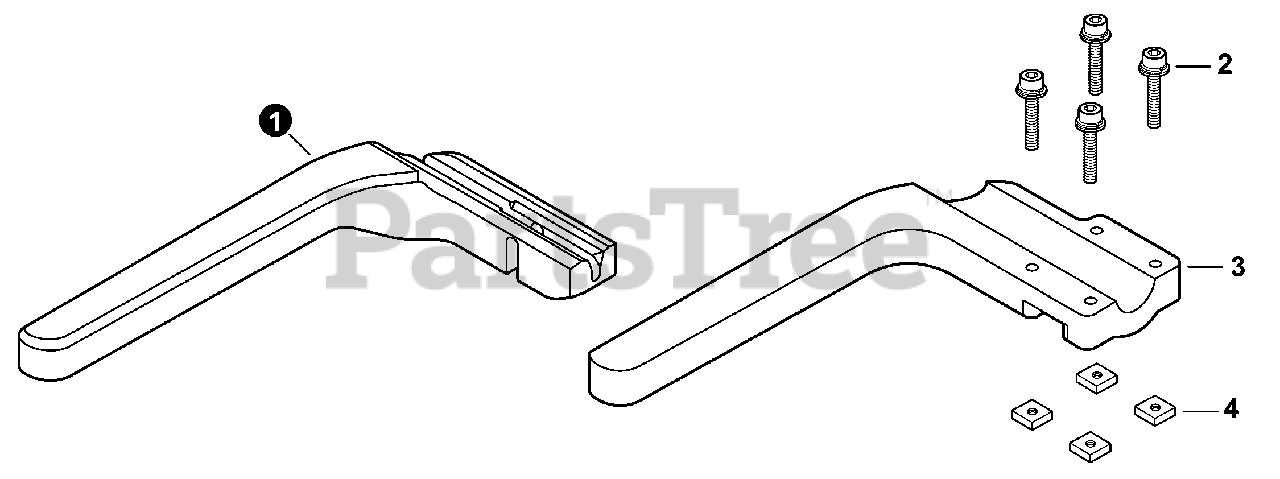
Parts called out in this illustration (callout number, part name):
1	BAR, BARRIER
2	BOLT M5×35
3	BAR, BARRIER
